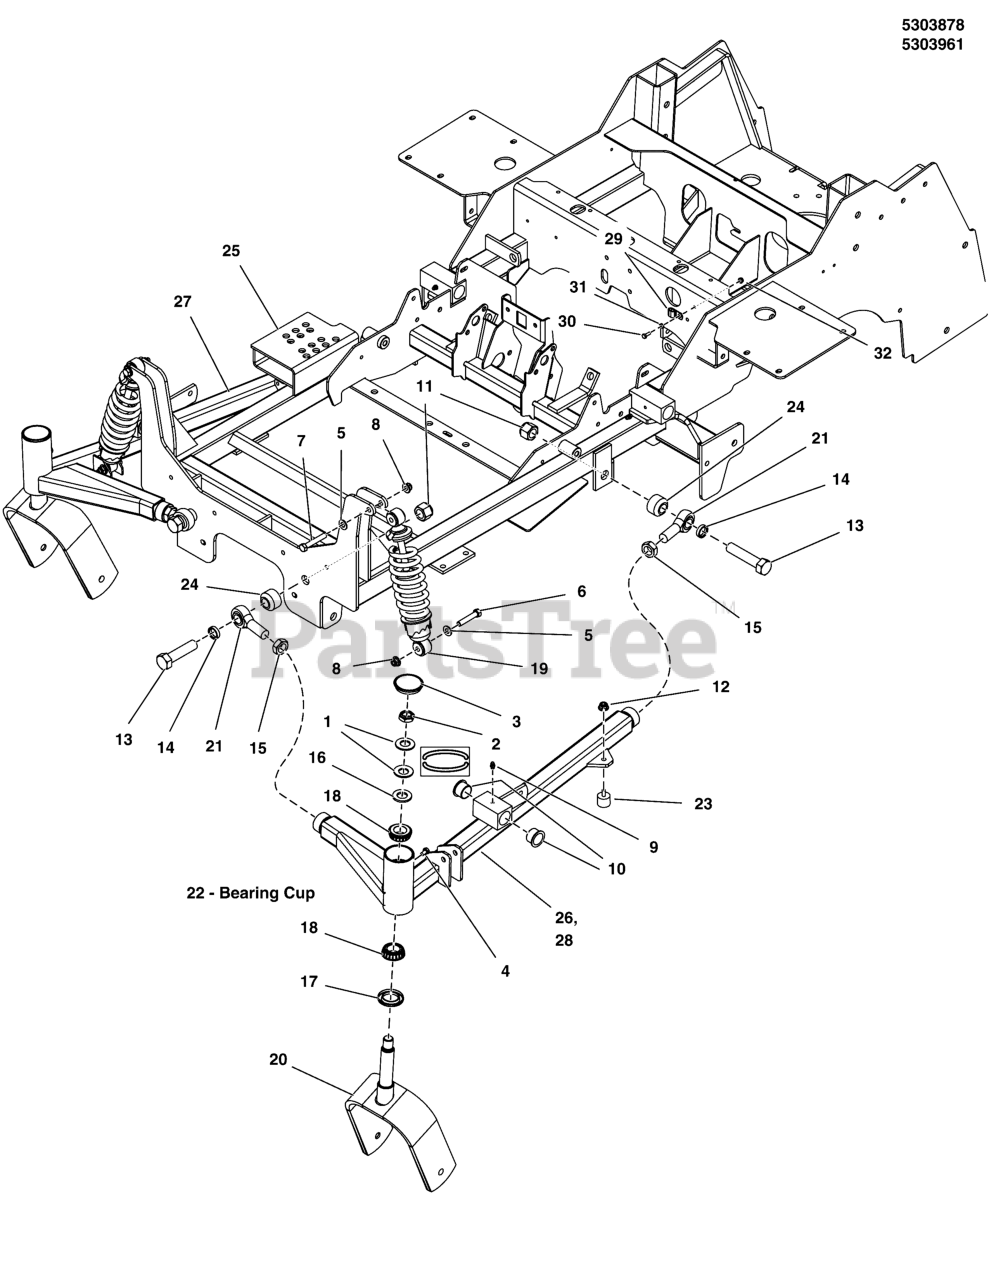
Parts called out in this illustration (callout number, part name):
1	WASHER, BELLEVILLE - 1.500 X .755
2	NUT, 3/4-16, HEX JAM NYLON LOCK
3	CAP, GREASE, LOW PROFILE
4	BOLT, 1/4-28 X 1/2, GD5 CZ
5	WASHER, 3/8 SAE
6	BOLT, 3/8-16 X 2, GD5, CZ
7	BOLT, 3/8-16 X 2-1/4" GD5 CZ
8	NUT, 3/8-16 HEX NYLOCK FLANGE
9	GREASE FITTING, 1/4-28 STRAIGHT
10	BUSHING, 1.00 X 1.13 X 1.38, PLASTIC
11	NUT, 3/4-16 HEX NYLON LOCK
12	NUT, 1/4-20 HEX SERR. FLANGE
13	BOLT, 3/4-16 X 3-1/2 GD8 CZ
14	SPACER, .76 X 1.00 X .25
15	NUT, 3/4-16 HEX JAM
16	WASHER, 3/4 SAE
17	SEAL, GREASE
18	BEARING, TAPERED ROLLER, 1
19	SHOCK / SPRING ASSEMBLY, OE22375
20	WELD, CASTER YOKE - RED
21	BALL JOINT, 3/4-16, MALE
22	BEARING, CUP (SV)
23	BUMPER, RUBBER 1/4-20
24	SPACER, .75 X 1.50 X 1.00, CZ
25	* WELD, MAIN FRAME, IS3200Z - RED
26	WELD, A-ARM, IS3200Z, LH - RED
27	WELD, A-ARM, IS3200Z, RH - RED
28	WELD, A-ARM, 72, LH - RED
29	CLAMP, 5/16, DOUBLE, WIRE & TUBE
30	BOLT, 1/4-20 X 3/4 GD5 YZ
31	WASHER, 1/4 SAE
32	NUT, 1/4-20 HEX NYLOCK FLANGE
